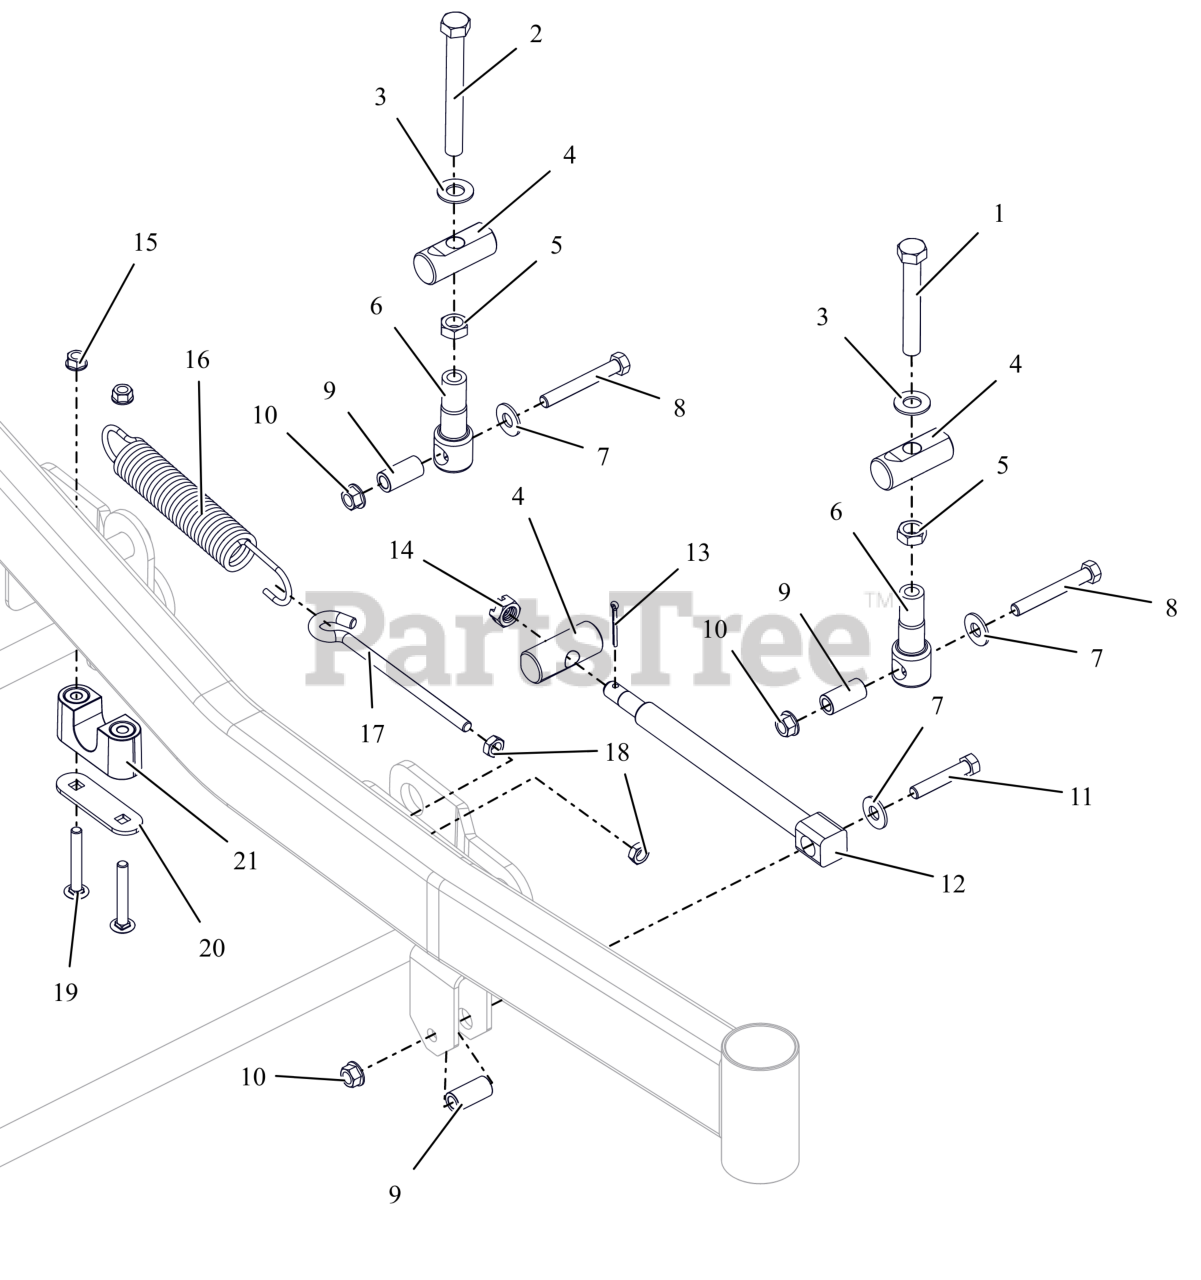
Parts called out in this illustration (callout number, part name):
1	BLT, HEX 0.5-13X3.5F GR5 ZCC
2	BLT, HEX .50-13X4.50F G8 ZCC
3	WSHR, FLT .557X1.040X.102 ZCC
4	PIN, DECK LIFT
5	NUT-JAM .500-13 G2 ZCC
6	LINK, DECK LIFT FORMED
7	WSHR,FLT .438X1.00X.083 ZCC
8	BLT, HEX .38-16X2.75 G8 ZCC
9	SPACER, DECK LEVELING
10	NUT-LK-TOP-FLG .38-16 ZC120
11	BLT,HEX .38-16X2.00 G5 ZCC
12	DRAG,LINK-HD
13	PIN,CTR.12X1.25EXTPRSQCT ZC120
14	NUT-SL .50-13
15	NUT,LK-CTR-FLG .31-18 GF ZCC
16	SG-TENS.162X1.25X8.25 E-COAT
17	BOLT- J-HOOK.38-16X5.25 E-COAT
18	NUT-JAM .375-16 GR2 E-COAT
19	BLT, RHSSN.31-18X2.25 G5 ZCC
20	PLATE, BEARING SUPPORT
21	ASM-BUSHING, DECK LIFT
